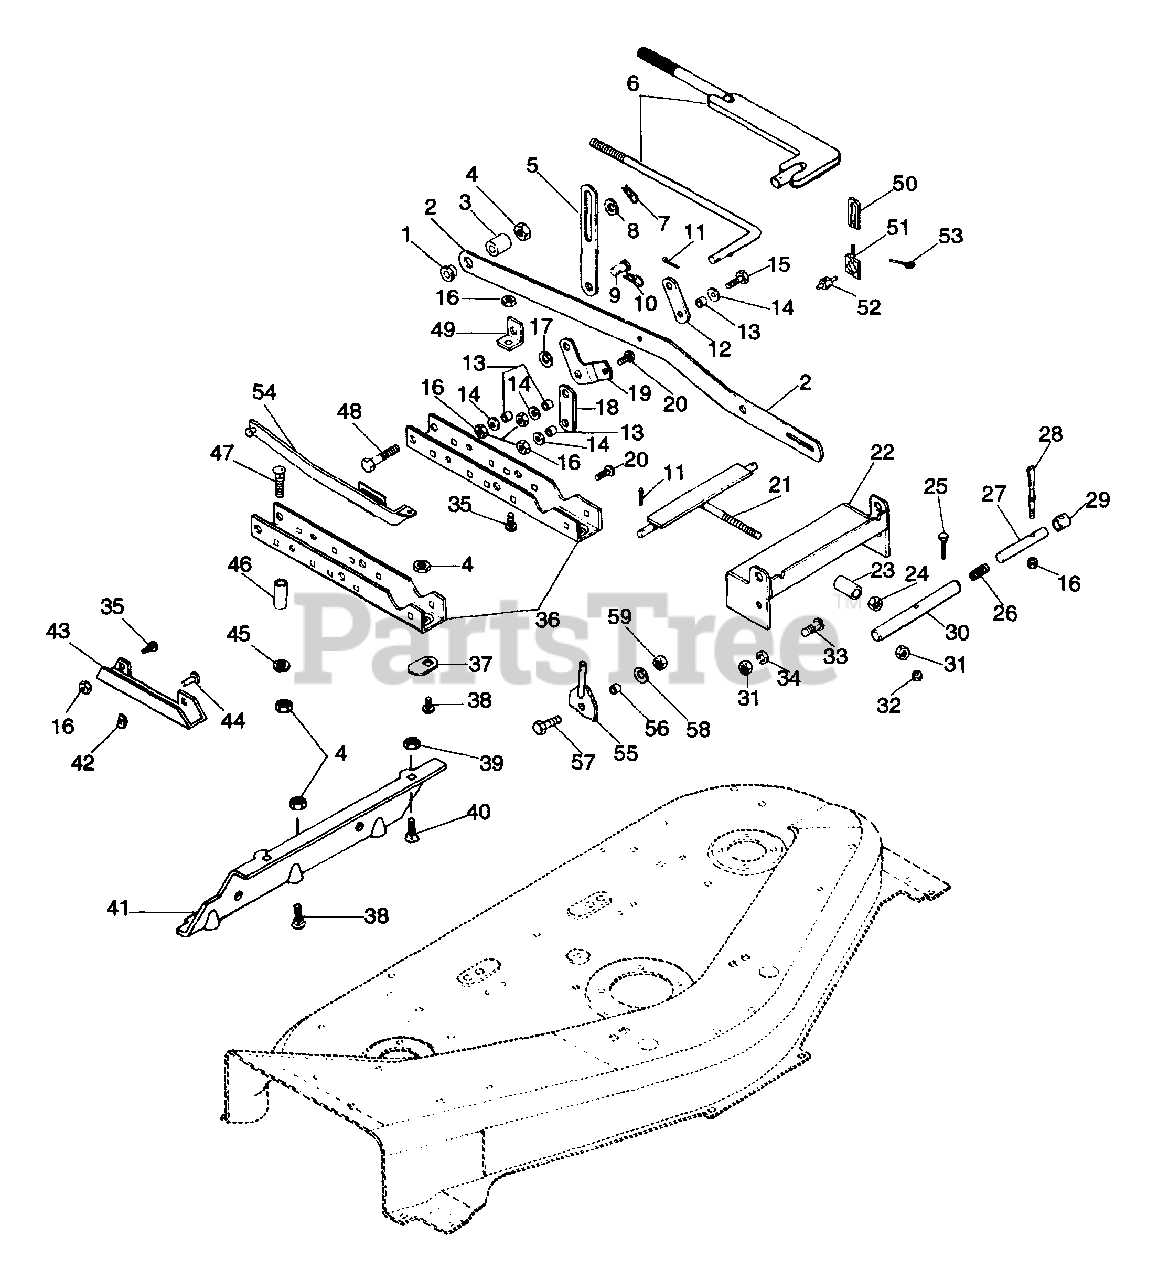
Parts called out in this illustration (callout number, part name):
1	BSHG-FLG .531X.750X.562X1.000
2	HANGER BAR
2	HANGER BAR R H
2	HANGER BAR L H
3	SPACER .531X1.000X1.188
4	NUT-LK-CTR .50-13
5	LIFT LINK
6	ADJUSTMENT ROD
6	PITCH ADJUSTER
7	PIN-HAIR INT .09X.188 PL
8	WSHR-FL-STL .531X1.062X.095 PL
9	CLEVIS PIN
10	PIN-HAIR INT .08X.38X1.42 YWZC
11	PIN-COTR .12X1.0 PL
12	STRAP
13	SPACER BUSHING .5 X .32 X .21
14	WSHR-FL-STL .328X.875X.062 PL
15	BLT-HEX .31-18X1.25 PL GR2
16	NUT-LK .312-18 GR A PL
17	WSHR-FL-STL .469X.937X.065 PL
18	ADJUSTMENT LINK
19	R H ADJUSTMENT LEVER
19	L H ADJUSTMENT
20	BLT-RDHDSQNK .31-18X.75 SHT PL
21	ADJUSTER
22	PIVOT BRACKET
23	SPACER .563X.875X1.500
24	NUT-JAM .50-13 PL
25	BLT-HEX .25-20X1.50 PL GR5
26	SG-COMP .048X.59X2.06 WLD9
30	TUBE .662 X .812 X 7.36
31	NUT .50-13 PL
32	NUT-LK-CTR .250-20 PL
33	BLT-RDHDSQNK .50-13X1.25 PL
34	WSHR-LK .500X.151 HVY PL
35	BLT-RDHDSQNK .312-18X.62 PL
36	CHANNEL
36	BRACKET
37	COVER
38	BLT-RDHDSQNK .50-13X.75 SHT PL
39	NUT-LK-CTR .375-16 GR A PL
40	BLT-RDHDSQNK .375-16X.75 PL
41	PLATE REAR MOUNTING
42	NUT-PUSH .312
43	BRACKET
44	RVT .312X.75 RH ST
45	WSHR-FL-STL .380X1.50X.125 PL
45	WSHR-FL-STL .505X.880X.072 PL
46	SPACER .512X.747X1.567
46	SPACER, PIVOT .500X.750X1.805
47	BLT-RDHDSQNK .38-16X2.75 GR5PL
47	BLT-RDHDSQNK .50-13X2.50SHTPL
48	BLT-HEX .50-13X2.50 PL GR5
49	BRACKET
50	LINK, ADJUSTMENT
51	HEX HANGER
52	HANGER PIVOT
53	PIN-COTR .09X.75 PL
54	LIFT ARM R H
54	LIFT ARM L H
55	ADJUSTMENT LINK
56	BSHG-SLV .377X.624X.235
57	@BLT-HEX .38-16X.88 PL GR2
58	WSHR-FL-STL .38X.875X.083 PL
59	NUT-LK-CTR .375-16 GR A PL
